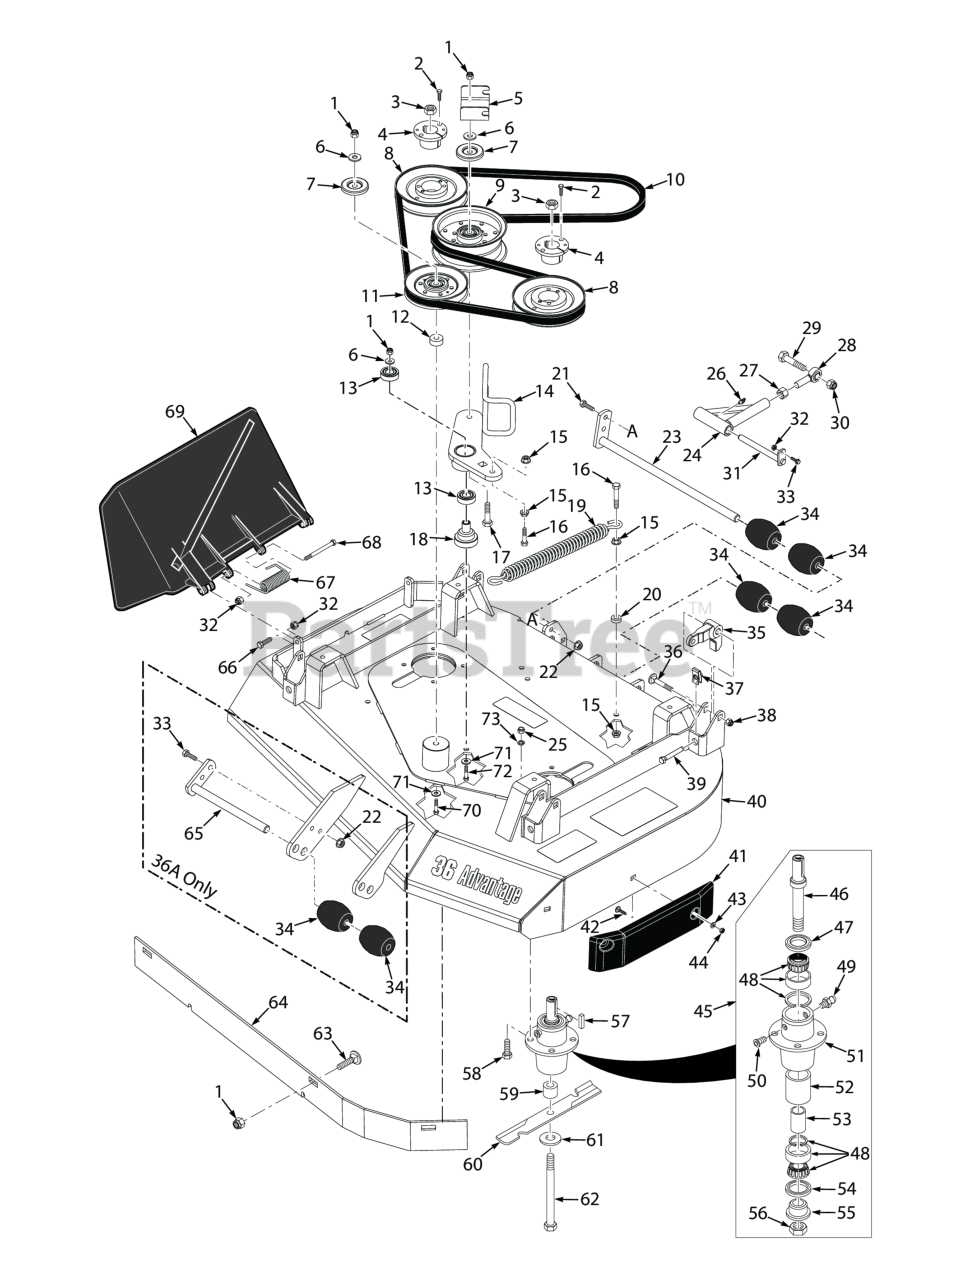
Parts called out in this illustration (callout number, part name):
1	HEX NUT, ELASTIC STOP LOCK, 3/8-16
2	Bolt, Hex Head 1/4-20 x 1" Grade 8 Black
3	Hex Locknut, Elastic Stop, 3/8-16
4	Hub, Tapered 1-1/8" Bore
5	Bracket, Belt Guide
6	Flatwasher, 3/8 (.391 x .938 x .105 HD) Grade 8
7	Quick Pin, 5/16" Dia.
8	Pulley, 5.13" Dia. - 48V
9	Pulley, Idler 5" Dia.
10	Belt, Cutter Deck
11	IDLER PULLEY, "V" GROOVE
12	SPACER, J PULL ROD
13	BEARINGS, BALL, NEUTRAL RETURN
14	Idler Arm Assembly
15	NUT, 3/8-16 SERRATED FLANGE HEX HEAD
16	Bolt, Hex Head 3/8-16 x 1-1/2" Grade 8 Black
17	Capscrew, Hex Head 3/8-16 x 3.25"
18	Pivot, Idler
19	Spring, Cutter Deck
20	SPACER, IDLER
21	Bolt, Carriage 5/16-18x1" (large frame units only)
22	Nut, Flange Head Elastic Stop 5/16-18
23	Shaft Weldment
24	Pusharm Assembly, LH
25	Lock Nut, 5/16-18 Elastic Stop Grade 8
26	Grease Fitting, 90 Degree
27	Nut, Hex Head 5/8-18 UNF
28	Rod End, 5/8" Male RH Thread
29	BOLT, HEX HEAD 5/8-11 X 4-1/2"
30	HEX LOCKNUT, ELASTIC STOP, 5/8-11
31	Shaft Weldment, Pusharm Mounting
32	HEX NUT, ELASTIC STOP LOCK, 5/16-18
33	Bolt, Heax Head 5/16-18 x 1" (48V / 52V)
34	Wheel, Anti-Scalp
35	Lever, Deck Level
36	Bolt, Carriage 7/16-14 x 2-1/4"
37	U-Nut, 3/8-16 (short)
38	HEX LOCKNUT, ELASTIC STOP, 7/16-14
39	Bolt, Hex Head 3/8-16 x 2-1/2" Soecial Lock
40	Cutter Deck w/Decals (32)
41	Pad, Deck Wear
42	Bolt, 5/16-18 x .75 RHSN Carriage
43	Flatwasher, 5/16-.344 x .688 x .065 (48V / 52V)
44	Nut, Center Lock, 5/16-18(32)
45	Spindle Assembly
46	Spindle Shaft, Tapered Brng
47	SEAL, 2.00 O.D. X 1.50 BORE
48	Tapered Bearing Set (Two Bearings W/Race)
49	GREASE FITTING, STR. 1/4-28 SELF TAP.
50	RELIEF FITTING, TAPERED BEARING SPINDLE
51	Housing, Spindle
52	Spacer, Outside, Cutter Spindle
53	SLEEVE, CUTTER SPINDLE
54	Seal, 2.00" O.D. x 1.625" Bore
55	SPINDLE BUSHING, BOTTOM
56	Nut , Spec ial 1 -1/ 1 6 - 1 8
57	Key, 1/4 x 1/4 x 2.0"
58	Bolt, Hex Head 5/16-18 x 1-3/4" Grade 8
59	Spacer, Spindle Bottom
60	Cutter Blade, 16-1/2" (48V)
61	Flatwasher, 5/8-.688 x 1-3/4 x .134 HD
62	BOLT, HEX HEAD, 5/8-11 X 9-1/2 GR.5
63	Carriage Bolt, 3/8-16 x 1.0"
64	Baffle, Flange (32)
65	Shaft Weldment, Guide Roller
66	Bolt, Hex Head 5/16-18 x 1-1/2" - Front
67	Spring, Discharge Chute
68	Bolt, 5/16-18 x 4-3/4" Hex Head
69	Discharge Chute Advantage - Small
70	Bolt, Hex Head 3/8-16 x 4-3/4"
71	Flatwasher, 3/8-.406 x 1-1-1/2 x 7 Gauge
72	Capscrew, Hex Head 3/8-16 x 3.25"
73	Lockwasher, 5/16 (.317 x .586 x .078) Helical Spring
